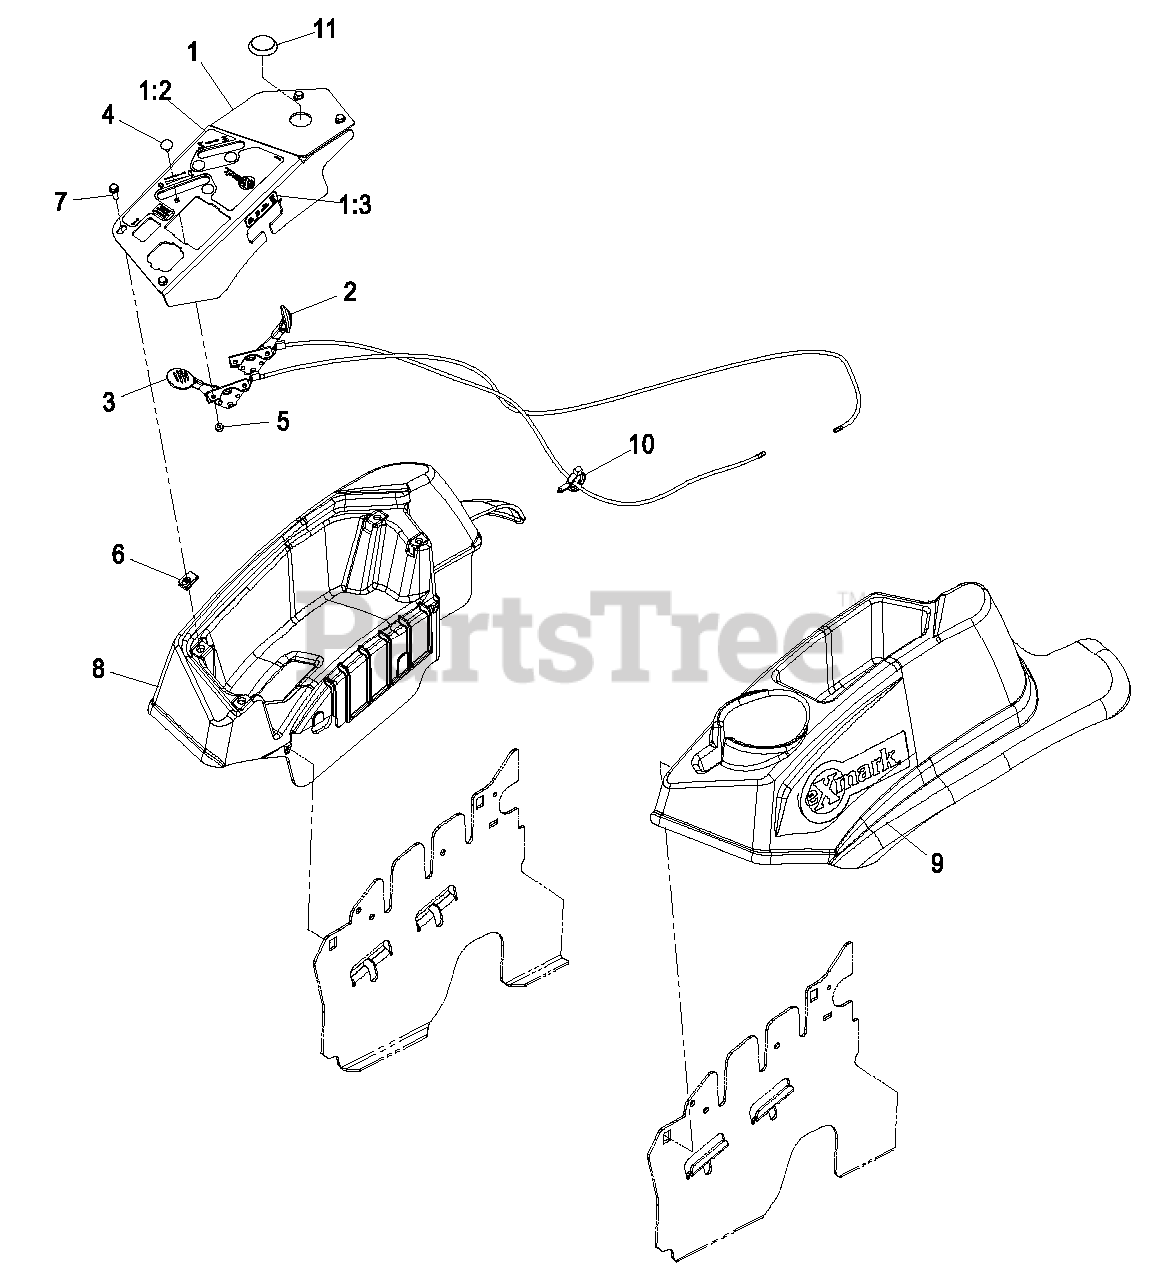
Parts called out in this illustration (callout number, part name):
1	CONSOLE,PANEL W/DECAL
1:2	DECAL-CONTROL PANEL
1:3	DECAL-FUSE
2	ASM, CHOKE CABLE
3	ASM,THROTTLE CABLE
4	BOLT-CARR
5	NUT-LOCK, NI
7	SCREW-HWH
8	CONSOLE,RH AS ASM
9	CONSOLE, LH AS
10	CLAMP-HOSE
